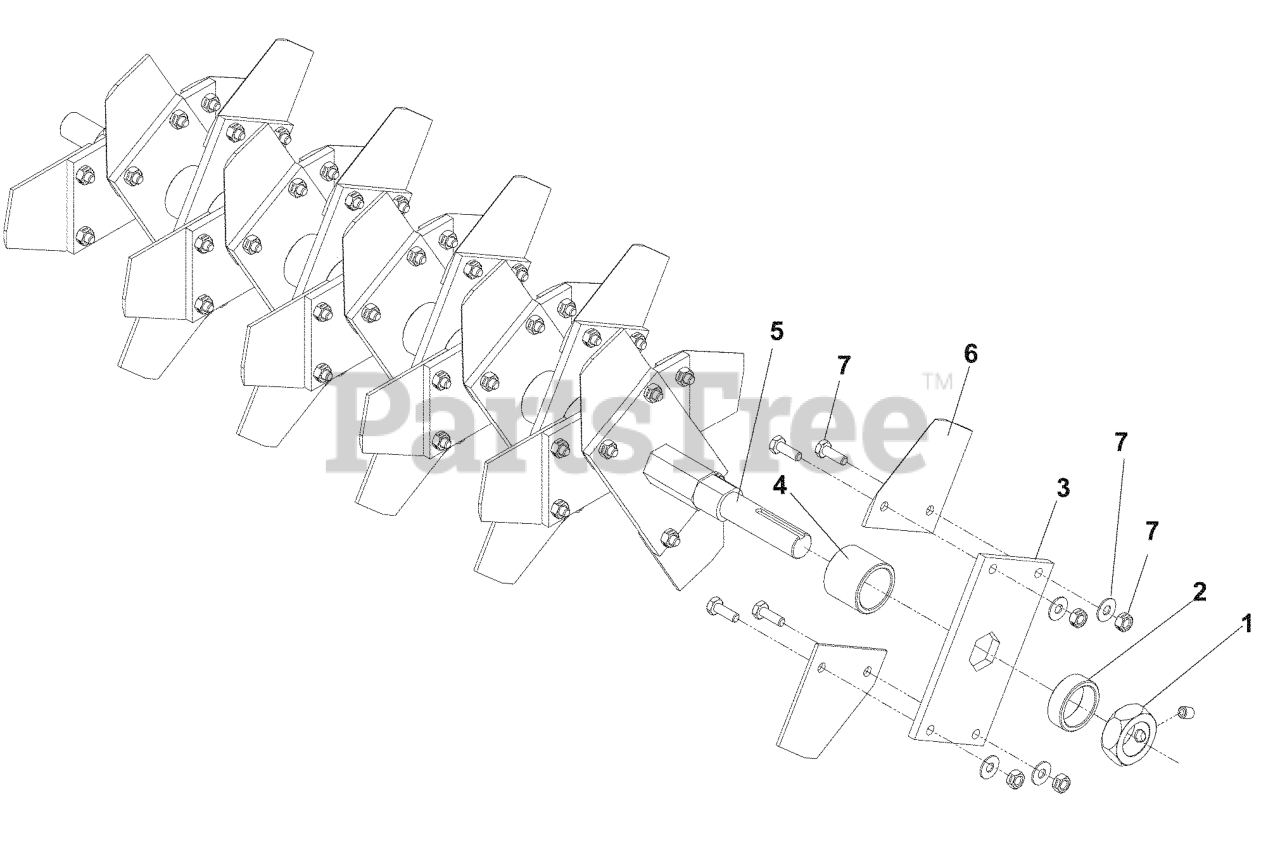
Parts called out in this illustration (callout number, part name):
1	JAM NUT W/SET SCREW
2	END SPACER
3	BLADE MOUNTING PLATE
4	SPACER - LONG
6	30 DELTA SET W/HARDWARE
7	SCREW & NUT (60 EACH)
